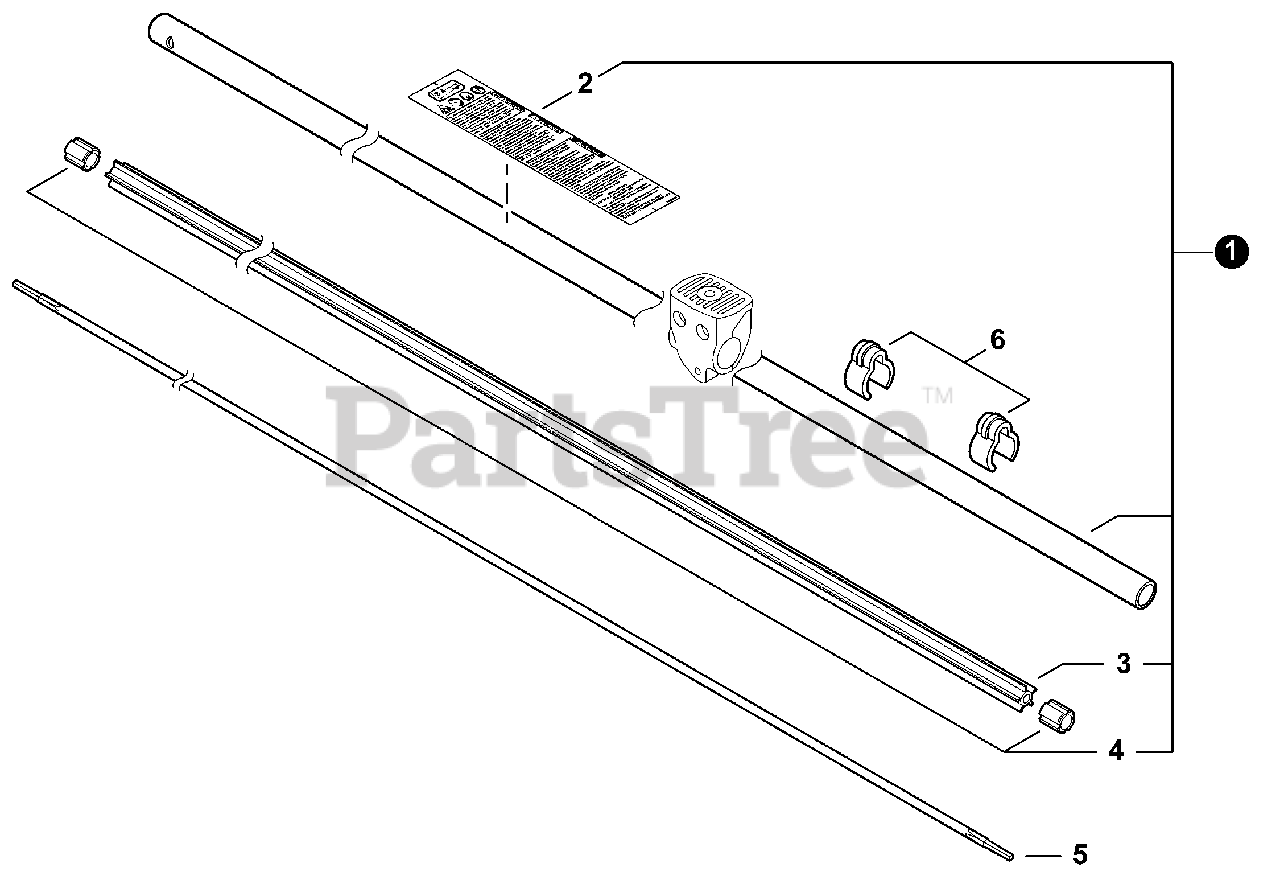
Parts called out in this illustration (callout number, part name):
1	MAIN PIPE ASSY
2	LABEL, CAUTION
3	LINER, FLEXIBLE 21.6×1420
5	DRIVESHAFT - FLEXIBLE
6	CLIP, CABLE 25 MM
